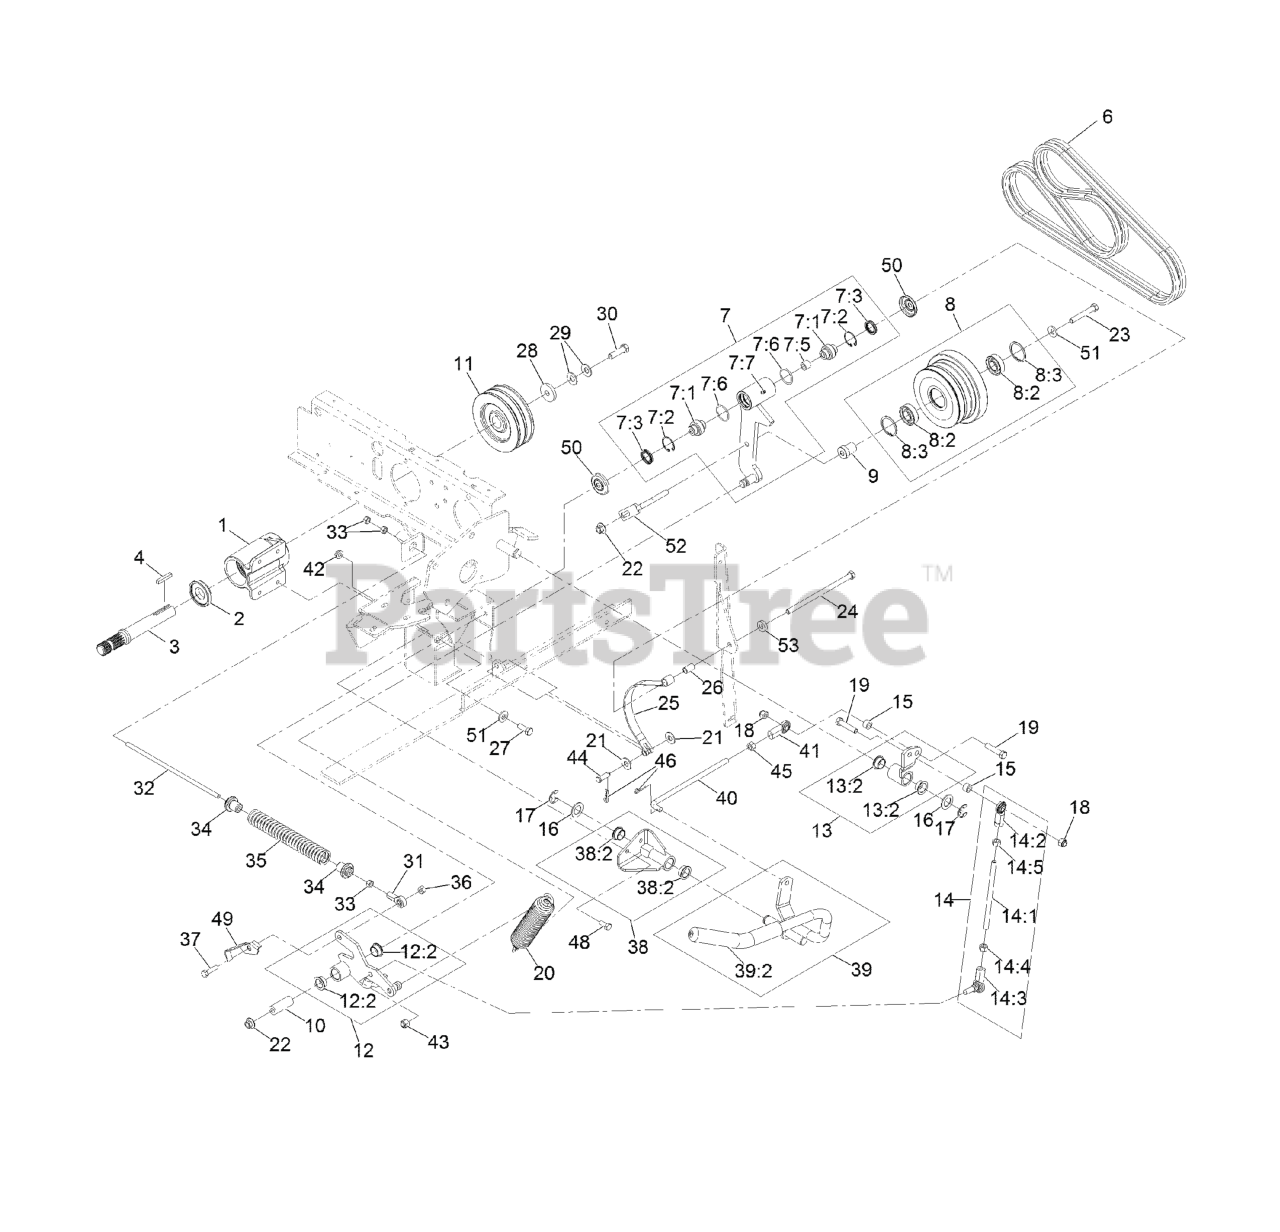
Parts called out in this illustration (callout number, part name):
2	SPACER-GUARD, BOTTOM
3	SHAFT-JACK
4	KEY-SQUARE
6	BELTS-MATCHED PAIR
7	IDLER PIVOT ASM
7:1	BEARING-SPHERICAL
7:2	RING-SNAP
7:3	SEAL-LIP, SINGLE
7:5	BUSHING-LEVER, LIFT
7:7	FITTING-GREASE
8	IDLER SHEAVE ASM
8:2	BEARING-BALL
8:3	RING-RETAINING
9	SPACER-IDLER
10	BUSHING
12	ARM ASM
12:2	BUSHING-BRONZE
13	ARM ASM
13:2	BUSHING-BRONZE
14	CLUTCH LINK ASM
14:1	ROD-LINKAGE
14:2	JOINT-BALL END, LH
14:3	BALLJOINT-RH
14:4	NUT-HEX
14:5	NUT-HEX, LH
18	NUT-LOCK, NI
19	SCREW-HH
20	SPRING-EXTENSION
21	WASHER-FLAT
23	SCREW-HH
24	SCREW-HH
25	BAND-BRAKE
27	SCREW-HH
28	WASHER-CLUTCH
29	WASHER-SPRING
30	SCREW-HH
31	BALLJOINT-RH
32	LINKAGE-ROD, PTO BRAKE
33	NUT-HEX
34	BUSHING-SPRING
35	SPRING-BRAKE
36	NUT-LOCK, NI
37	SCREW-HH
38	PIVOT ASM
38:2	BUSHING-BRONZE
39	PTO HANDLE ASM
39:2	GRIP-LEVER, CONTROL
40	LINK-HANDLE
41	JOINT-BALL, END
43	NUT-LOCK
44	PIN-CLEVIS
45	NUT-HEX
46	PIN-COTTER
48	SCREW-HH
49	SWITCH-FLAG
50	GUARD-TOP
51	WASHER-BELLEVILLE
52	GUIDE-BELT
53	SPACER
